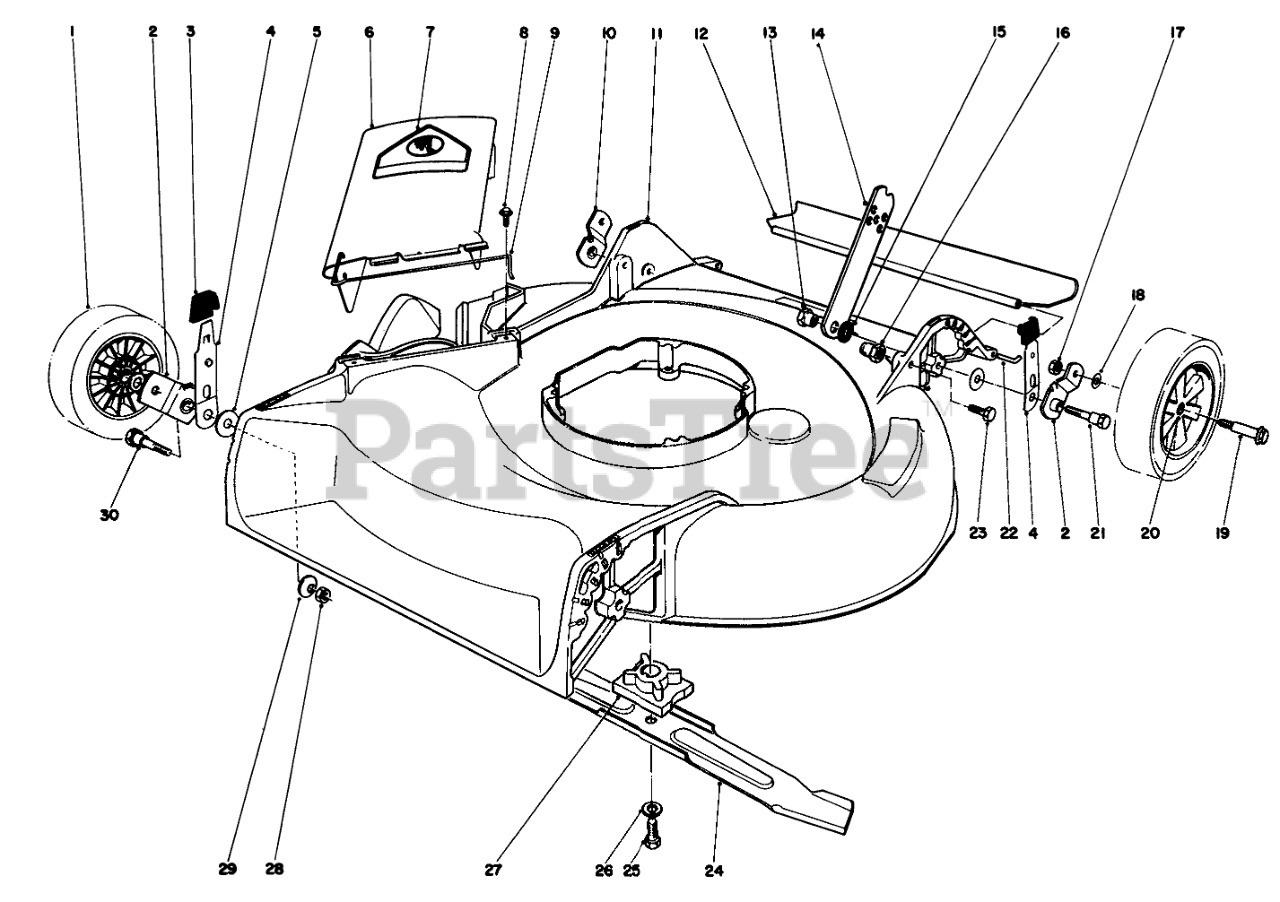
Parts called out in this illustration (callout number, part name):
1	Wheel & Tire Assembly (Incl. Ref. #20)
2	Pivot Arm
3	KNOB-ARM
4	SPRING ARM ASM
5	WASHER-PIVOT
6	Deflector Assembly (Incl. Ref. #7 & 9)
7	DECAL-DANGER
8	SCREW-HWH
9	SPRING HINGE
10	Pivot Arm
11	HOUSING/DECAL
12	REAR SAFETY SHIELD 21
13	HANDLE PIVOT NUT
14	HANDLE LATCH
15	SPACER
16	HANDLE PIVOT NUT
17	Nut
18	WASHER
19	BOLT-WHEEL
20	BUSHING
21	PIVOT SCREW
22	SHIELD ROD
23	SCREW-HH
24	Blade
25	SCREW-HH
26	WASHER-LOCK
27	BLADE RETAINER
28	NUT-LOCK, NI
29	WASHER-BELLEVILLE
30	5/16-18 PIVOT SCREW
